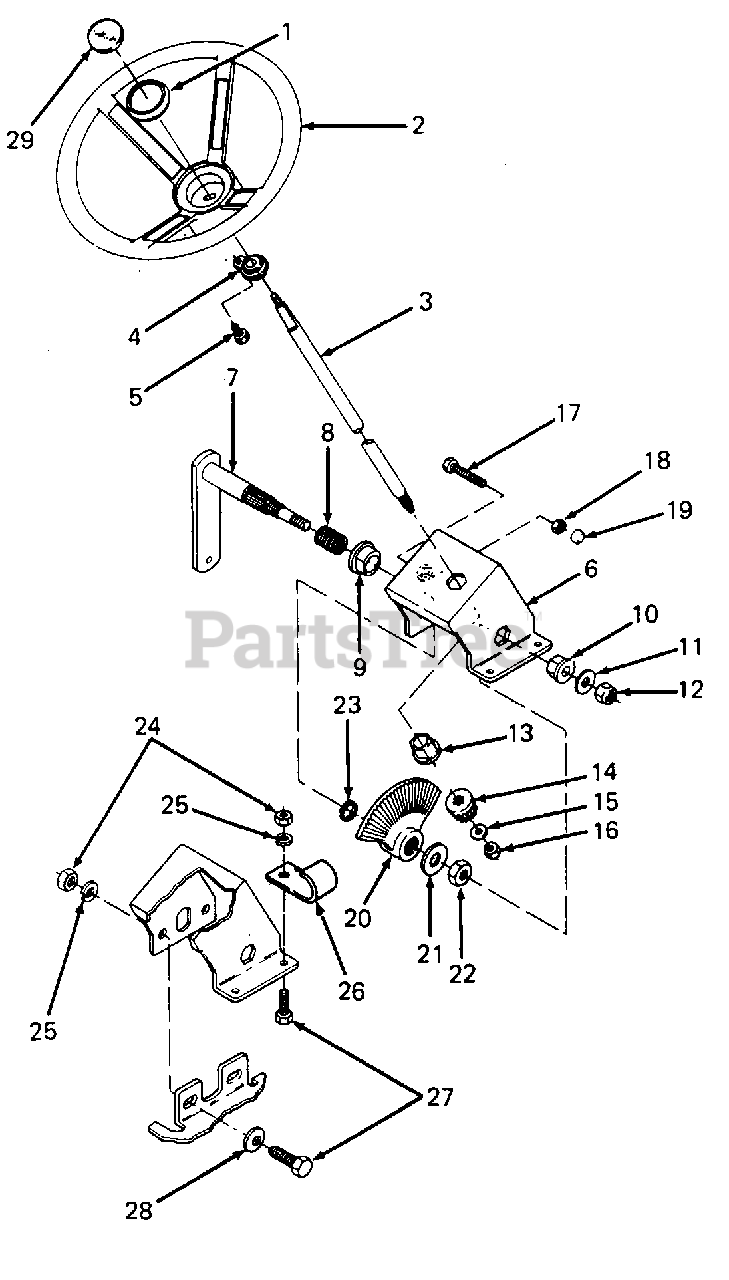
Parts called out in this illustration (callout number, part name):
1	Cap, Steering Wheel
2	Wheel, Steering
3	Shaft, Steering Wheel
4	Bearing, Steering Column
5	Screw, Oval Hd Cnt. Sunk, #10 X .62 Lg
6	Box, Steering
7	Shaft, Steering
8	Spring, Compression
9	Bearing, Flange
10	Bearing, Flange
11	Washer, Flat, .515 X 1.12 X .100 Thk HDN
12	Nut, Hex Center Lock, 1/2-13 GR5
13	Bearing, Flange
14	Gear, Pinion
15	Washer, Flat, .320 X .60 X .06 Thk HDN
16	Nut, Hex Center Lock, 5/16-24
17	Screw, Hex, 3/8-16 X 2.25 Lg GR5
18	Nut, Hex Jam, 3/8-16 GR5
20	Gear, Bevel
21	Washer, Flat, .640 X 1.25 X .06 Thk
22	Nut, Hex Jam, 5/8-18
23	Ring, Snap
24	Nut, Hex, 5/16-18 GR5
25	Washer, Lock, 5/16
26	Clip, Cable
27	Screw, Hex Cap, 5/16-18 X 1.0 Lg GR5
28	Washer, Bell, .345 X .88 X .060 Thk
29	Label, Steering Cap
